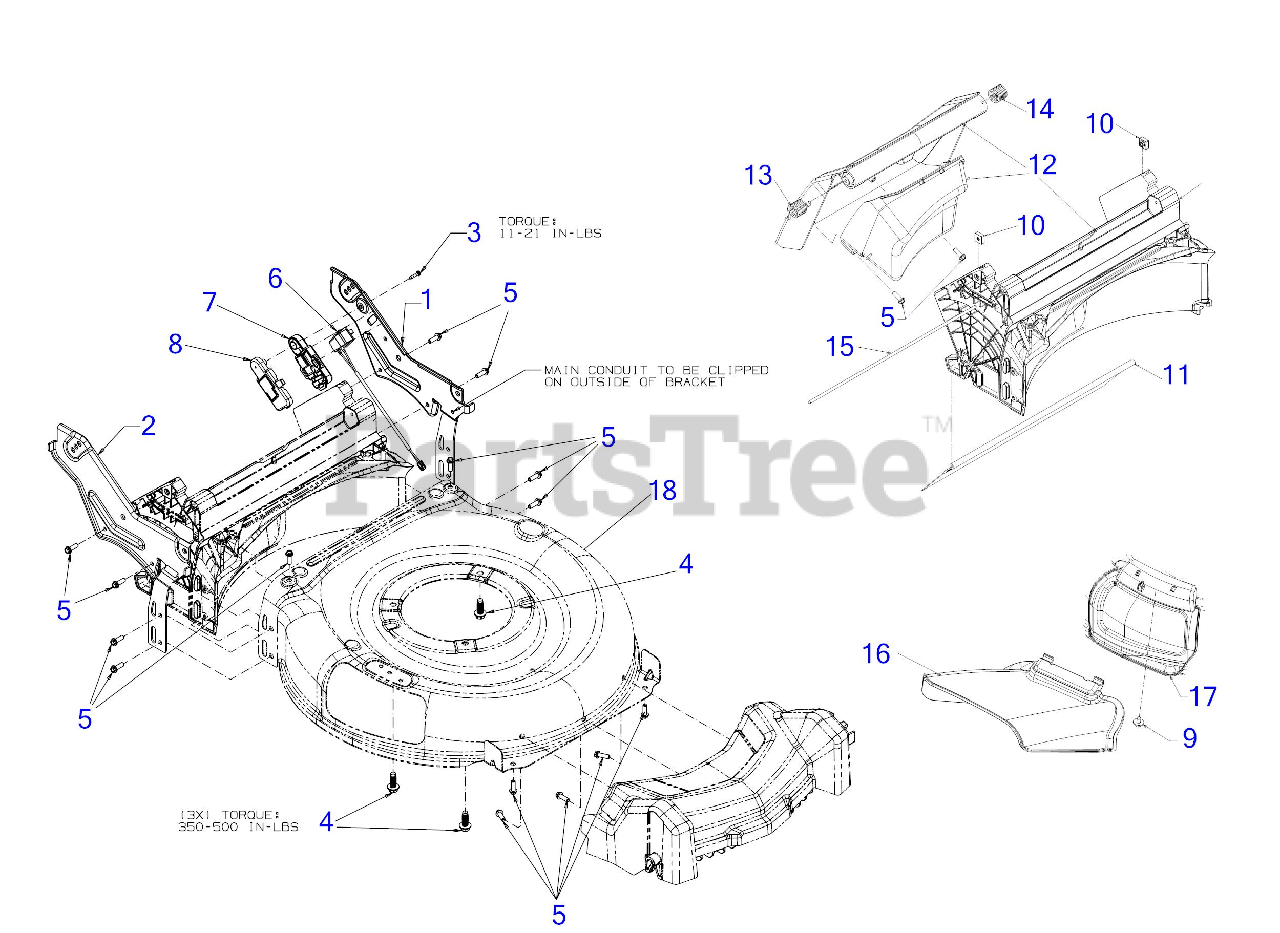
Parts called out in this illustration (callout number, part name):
1	HANDLE BRACKET (LH)
2	HANDLE BRACKET (RH)
3	SCREW 7-18X.75:T20
4	SCREW 3/8-16 x 1
5	SCREW 1/4 x .750
6	ROCKER SWITCH
7	UPPER HOUSING HANDLE SWITCH
8	LOWER HOUSING HANDLE SWITCH
9	SCREW 1/4-20 x .50
10	SQUARE LOCK NUT 1/4X20
11	TRAILSHIELD
12	REAR DISCHARGE DOOR ASSEMBLY
13	TORSION SPRING (RH)
14	TORSION SPRING (LH)
15	Order 631-05352
16	SIDE DISCHARGE CHUTE
17	MULCH PLUG ASSEMBLY
